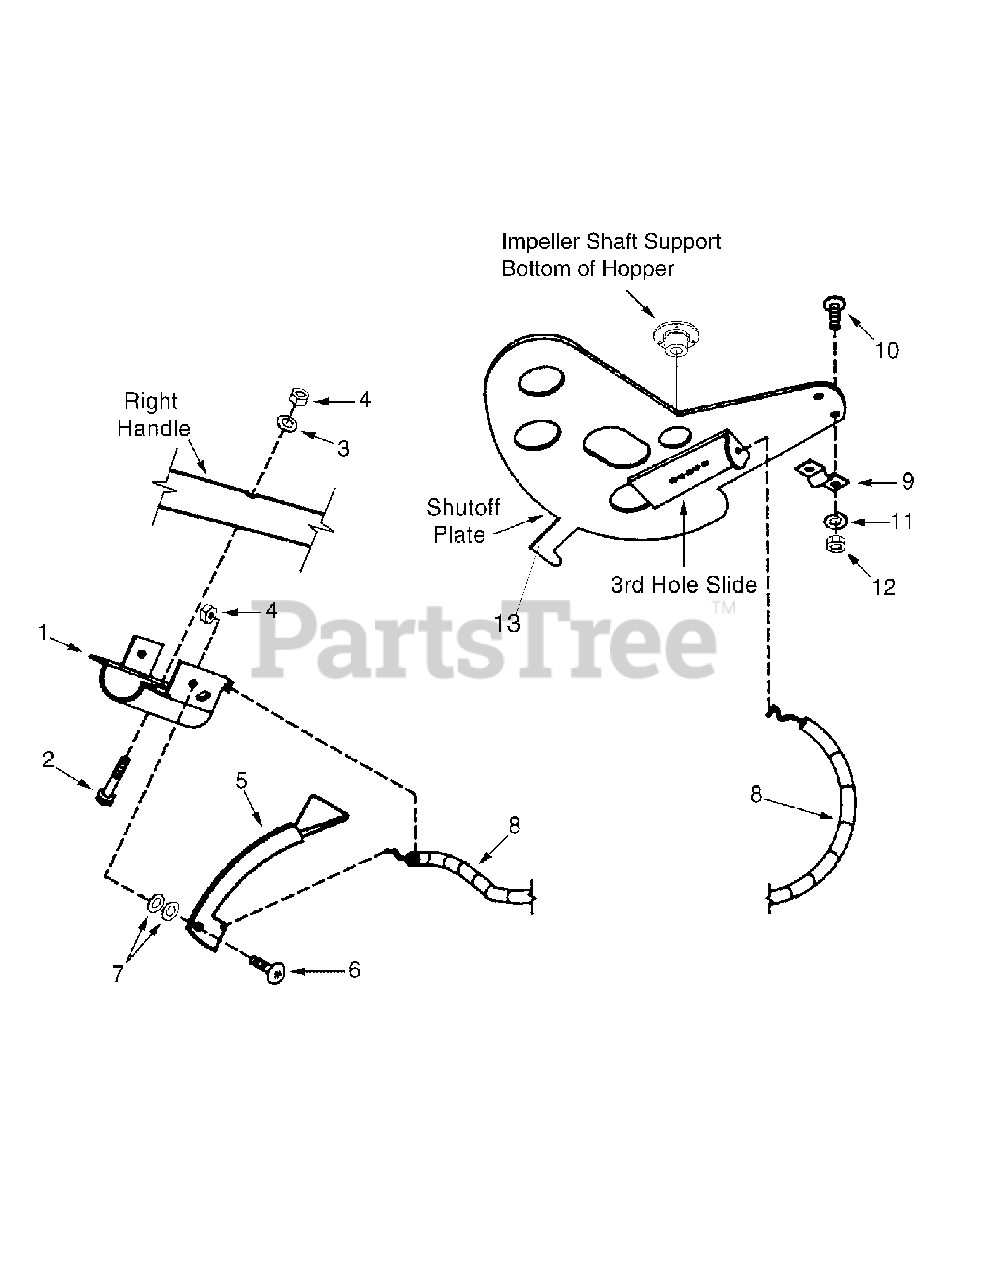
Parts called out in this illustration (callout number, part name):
1	Bracket, Dual Lever
2	Machine Screw
3	Flat Washer 1/4
4	Hex Nut, 1/4-20 Nylock
5	Lever, Dual Remote
6	Machine Screw
7	Flat Washer, 1/4 Nylon
8	Control Cable
9	Cable Clamp
10	Machine Screw
11	Lock Washer #8
12	Hex Nut, #8-32
13	Shut off Plate Assembly
13	Remote Shut off Plate
13	Slide Lever
